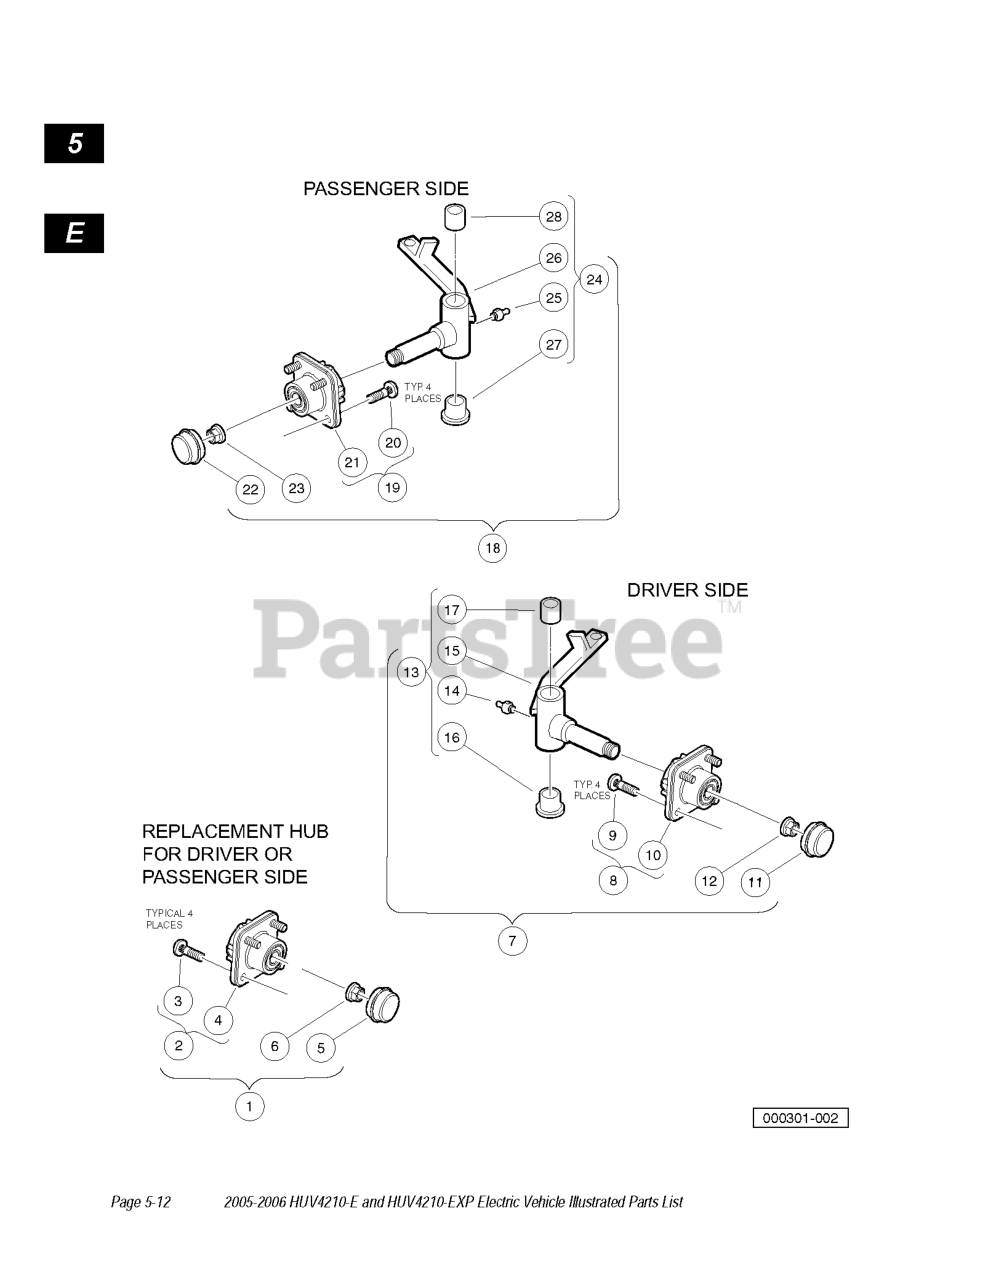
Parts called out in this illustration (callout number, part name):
1	REPLACEMENT KIT, FRONT HUB
3	LUG STUD, 1/2-20 UNF, 4037 STL
5	CAP, FRONT HUB
6	HEX NUT, LOCKING FLANGE, M14X2
9	LUG STUD, 1/2-20 UNF, 4037 STL
11	CAP, FRONT HUB
12	HEX NUT, LOCKING FLANGE, M14X2
13	ASM, SPINDLE, LH, EXT
14	FITTING, 1/4-28 THRD FRM GREAS
15	Subasm, Spindle, LH, Ext
16	BUSHING, FLANGED BROZE
17	BUSHING BRONZE SPINDLE
20	LUG STUD, 1/2-20 UNF, 4037 STL
22	CAP, FRONT HUB
23	HEX NUT, LOCKING FLANGE, M14X2
24	ASM, SPINDLE, RH, EXT
25	FITTING, 1/4-28 THRD FRM GREAS
26	Subasm, Spindle, RH, Ext
27	BUSHING, FLANGED BROZE
28	BUSHING BRONZE SPINDLE
